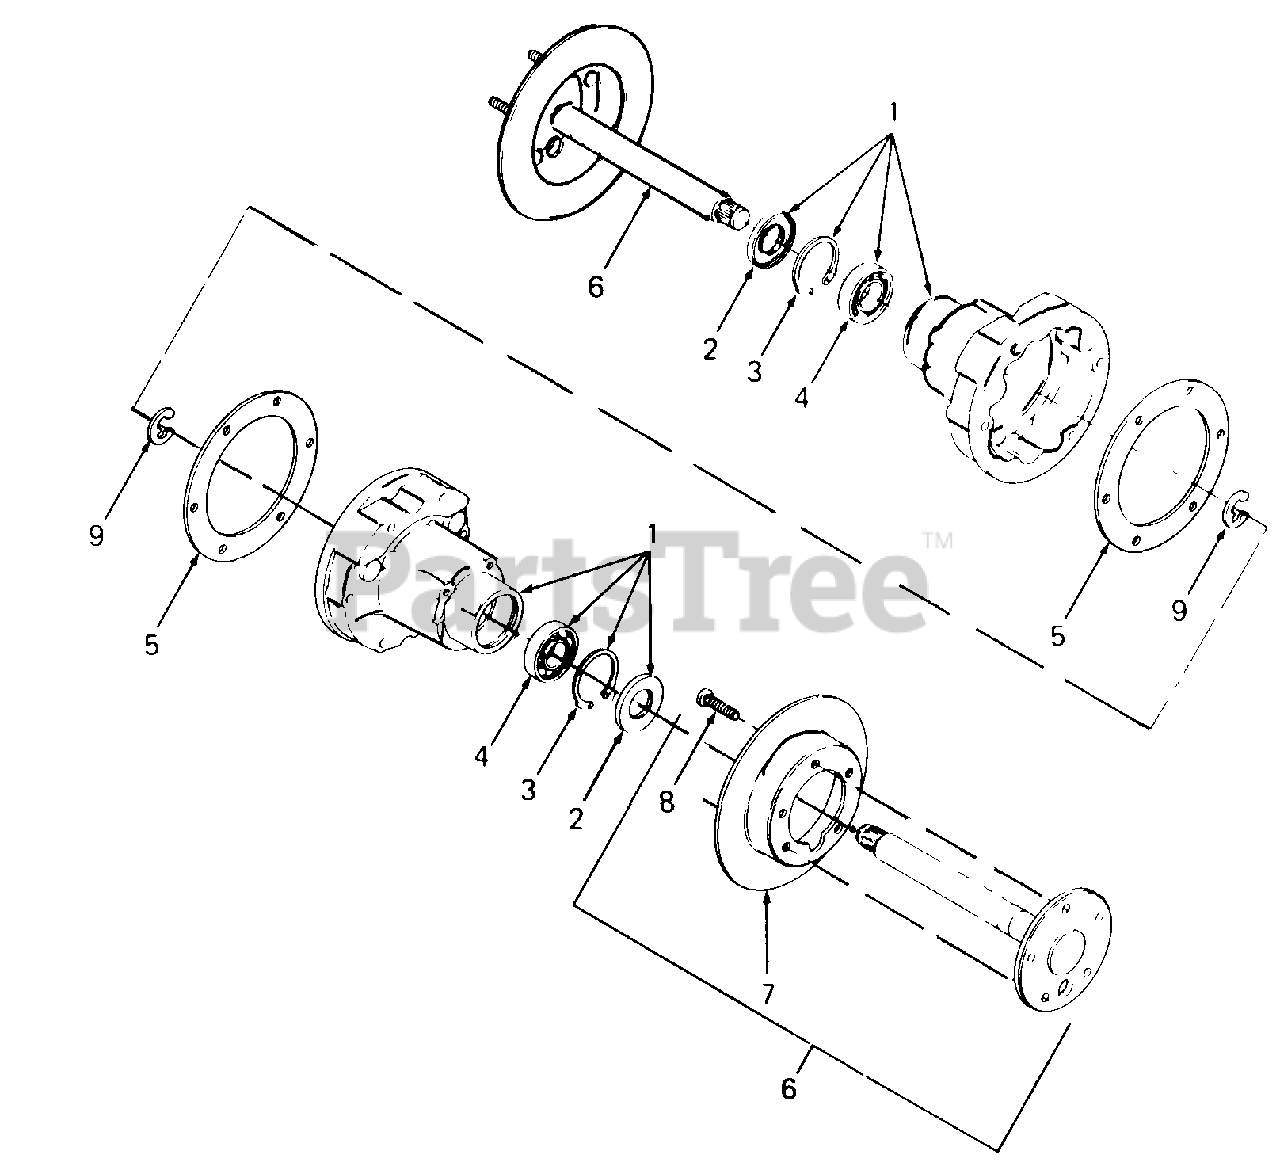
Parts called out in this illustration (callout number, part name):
1	Carrier Assy, Rear Axle
2	Seal, Oil
3	Ring, Retaining
4	Bearing, Ball
5	Gasket, Carrier
6	Axle Assy, Rear
7	Disc, Brake
8	Bolt, Lug
9	Retainer, E-Ring
